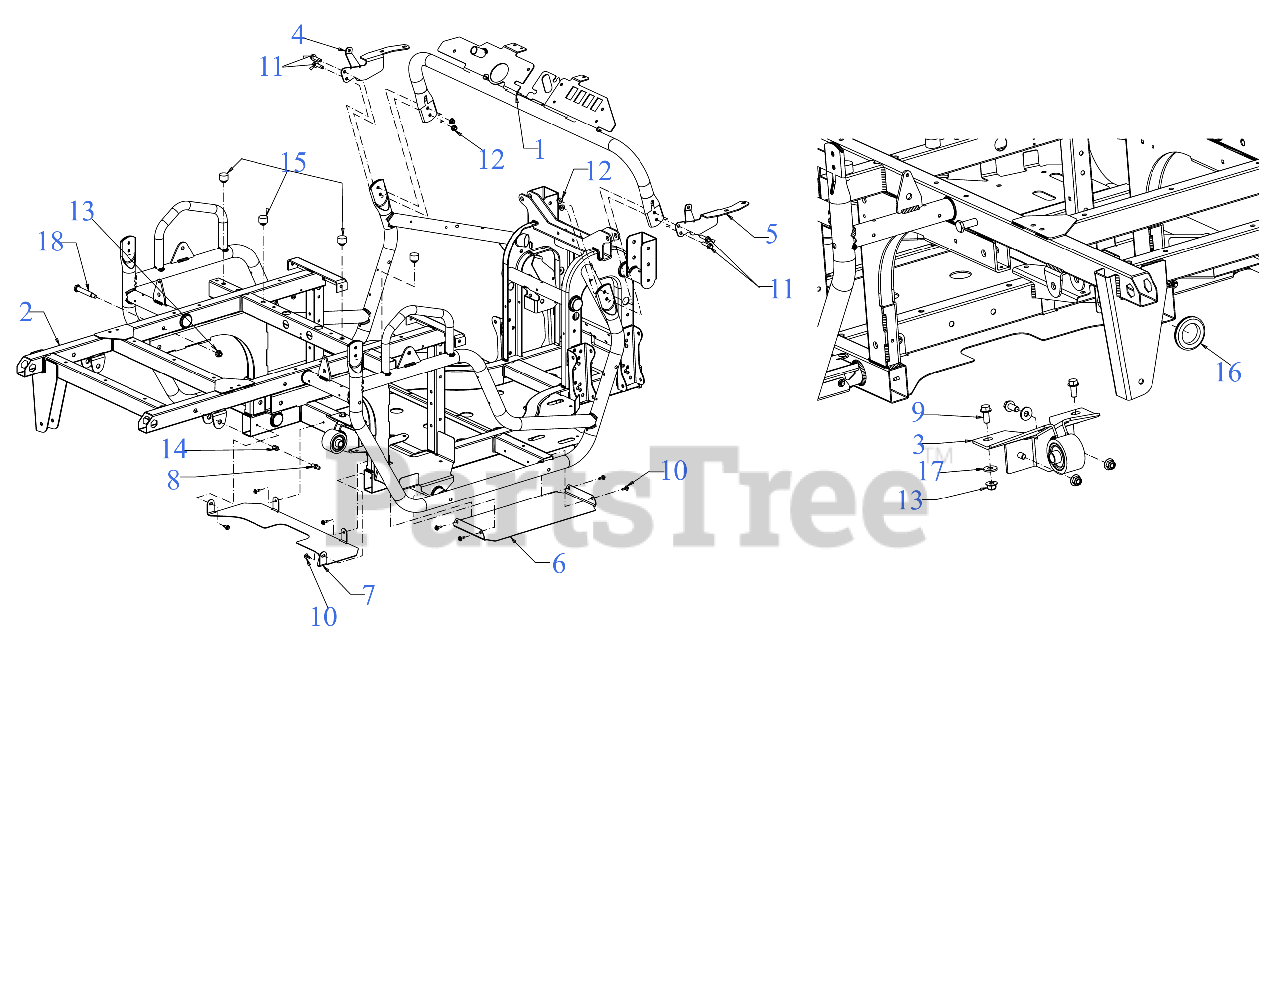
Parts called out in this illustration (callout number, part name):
1	DASH FRAME ASSEMBLY
4	HOOD FRAME BRACKET (LH)
5	HOOD FRAME BRACKET (RH)
8	BALL STUD 5/16-18
9	SCREW 3/8-16 x .875 GR5
10	SCREW M6-1 x .625
11	SCREW 5/16-18 x 1.25 GR5
12	FLANGE LOCK NUT 5/16-18
14	NUT RIVET 5/16-18
15	RUBBER BUMPER
16	RUBBER GROMMET
18	SHOULDER SCREW .500X 2.62: 3/8-16
